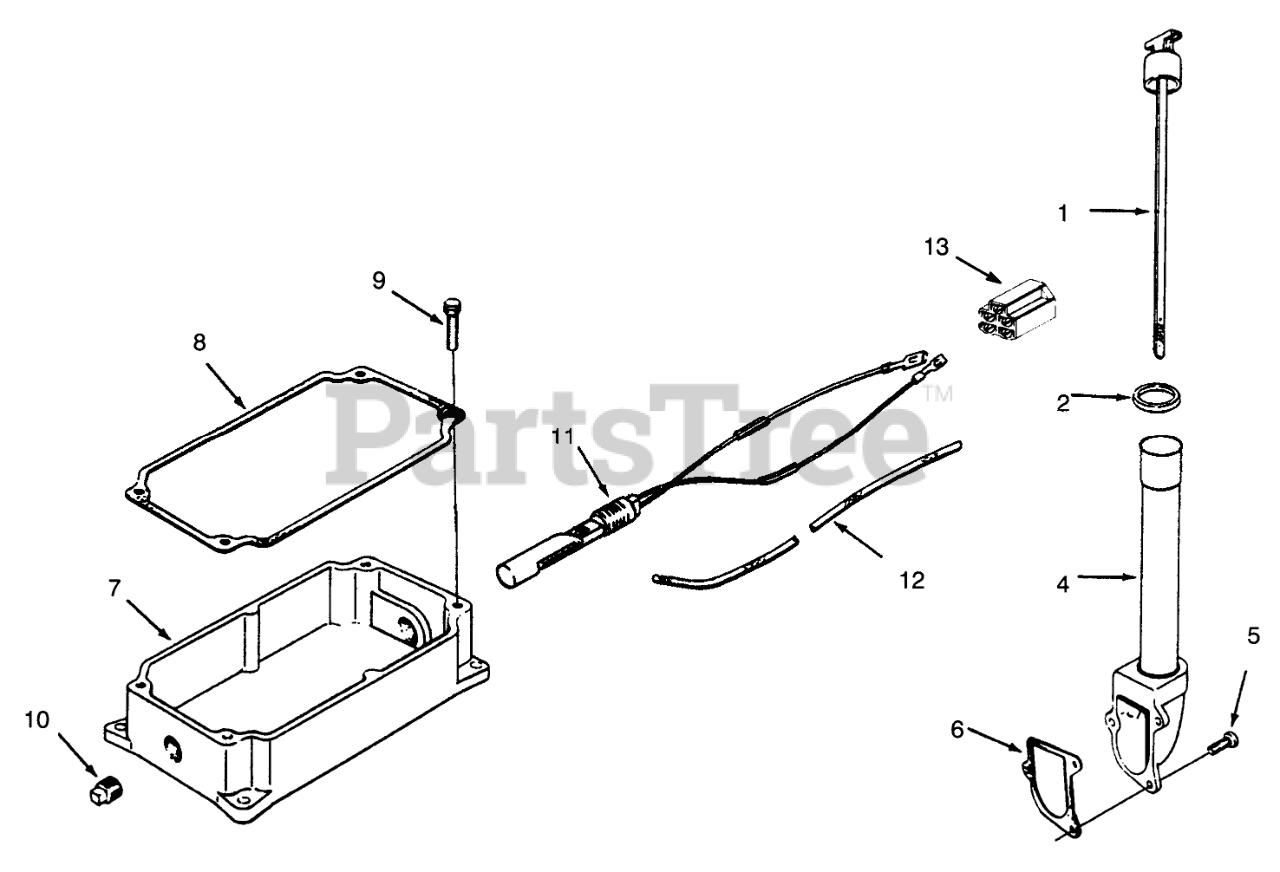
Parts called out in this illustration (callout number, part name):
1	Dipstick
2	0-Ring
4	Adapter-Oil Fill
5	Screw
6	Gasket
7	Oil Pan
8	Gasket
9	Screw
11	Kit-Float Switch (Incl. Ref.#12 & Decal)
12	Sleeve
13	Connector
